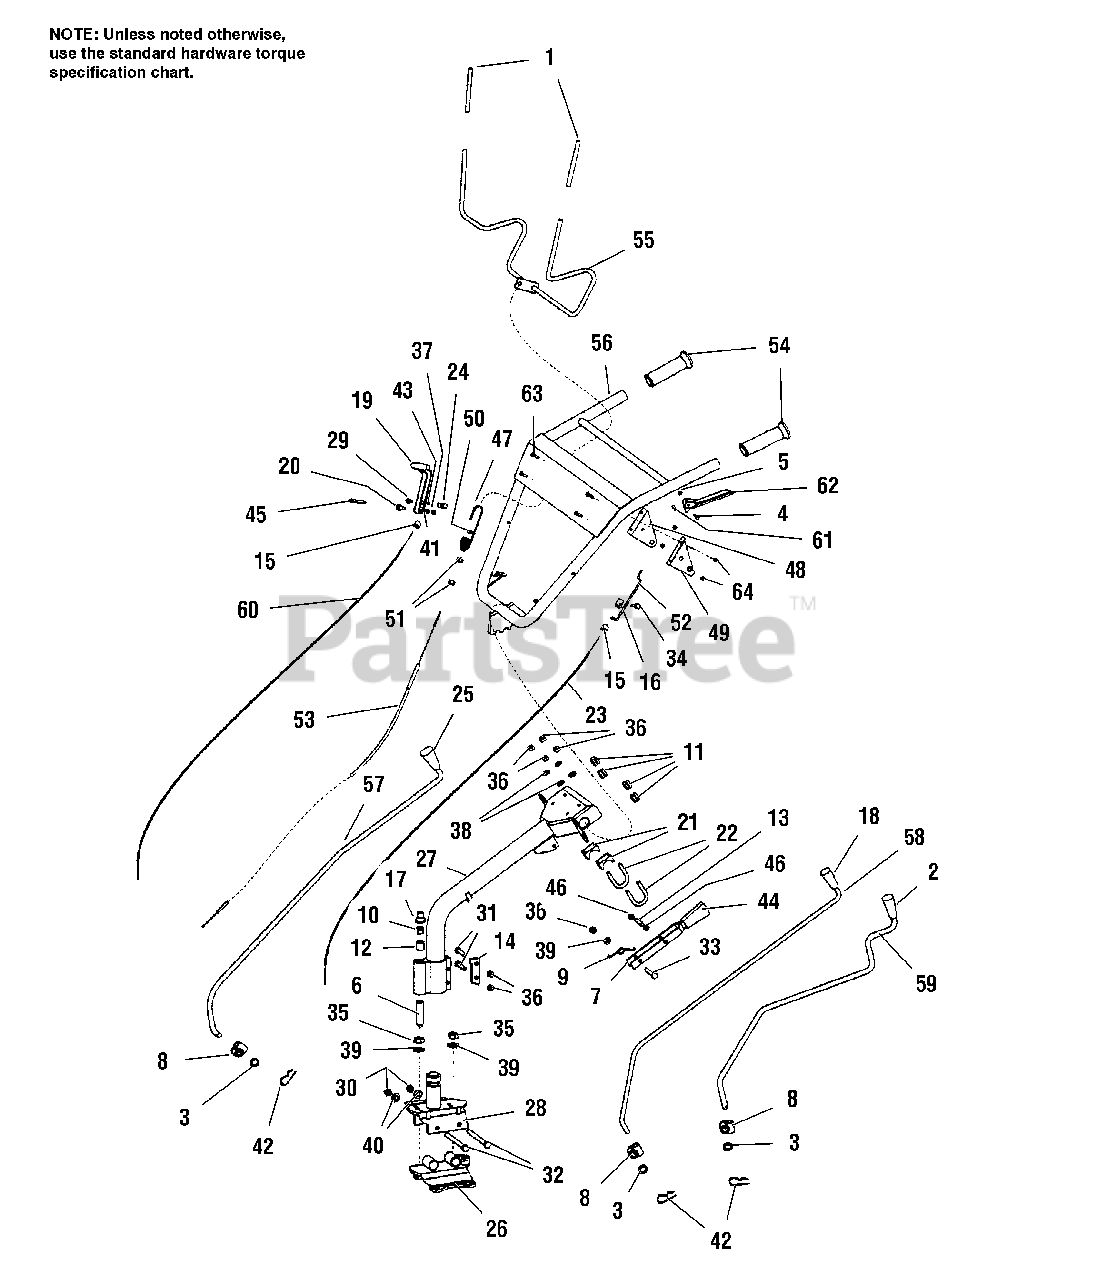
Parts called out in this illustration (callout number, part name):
1	HANDLE GRIP-Drive Control Lever
2	KNOB-Black, Direction Shift Rod
4	BOLT-Hex Hd, 1/4-20 x 1-1/4"
5	NUT-Keps, 1/4-20
6	PIN-Swivel Lock
8	PLASTIC PIVOT
9	SPRING-Tilt Lever
10	SPRING-Swivel Lock
11	RUBBER GROMMET
12	CABLE END-Swivel, Threaded
13	PIN-Latch, Tilt Lever
14	BASE LOCK PLATE
15	SHEATH END-Cable
16	CABLE LOCK HOLDER
17	SHEATH END-Lower
18	KNOB-Green, Tine Engage Rod
19	FREE WHEEL LEVER
20	BUSHING-Free Wheel Lever
21	TILT FRICTION PAD
23	CABLE ASSEMBLY-Swivel Lever
24	CABLE CLAMP
25	KNOB-Orange, Gear Shift Rod
26	HANDLEBAR BASE-Lower
27	HANDLEBAR STEM
28	HANDLEBAR BASE-Upper
29	BOLT-Cable Clamp, 6mm x 22mm
31	BOLT, 8mm x 30mm
33	BOLT, 8mm x 45mm
34	BOLT, 5mm x 10mm
35	NUT, 8mm x 1.25mm
36	LOCKNUT, 8mm
37	LOCKNUT, 6mm
38	WASHER-Flat, 8mm
39	WASHER-Wavy, 8mm
40	WASHER-Spring, 8mm
41	WASHER-Flat, 6mm
43	BALL-Cable Lock, 3/16"
44	KNOB-Plastic
45	BOLT, 6mm x 55mm
47	SPRING-Bee Hive, Forward Cable Adjust
48	BRACKET-Drive Control Lever, Right
49	BRACKET-Drive Control Lever, Left
50	NUT-Nyloc, #10
51	NUT-Jam, 5/16-24
52	REVERSE LINK
53	CABLE ASSEMBLY-Drive Control Lever
54	HANDLE GRIP, Black, 1" No Flange
55	DRIVE CONTROL LEVER
56	HANDLEBAR-Upper
57	GEAR SHIFT ROD
58	TINE ENGAGE ROD
59	DIRECTION SHIFT ROD
60	CABLE ASSEMBLY-Free Wheel Lever
61	BUSHING-Swivel Lever
62	SWIVEL LEVER
63	BOLT-Hex Hd, 5mm x 0.8mm x 10mm
64	NUT-Nyloc, 5mm x 0.8m
